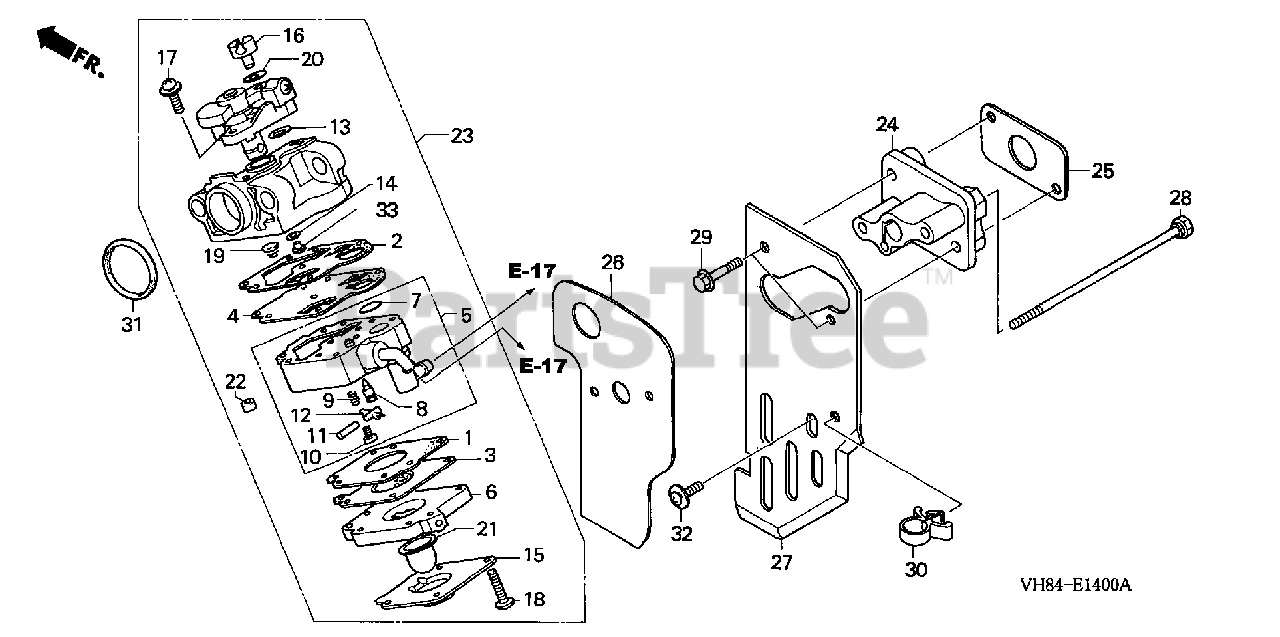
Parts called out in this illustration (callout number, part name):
1	GASKET, METERING DIAPHRAGM
2	GASKET, PUMP
3	DIAPHRAGM ASSY., METERING
4	DIAPHRAGM, PUMP
5	BODY ASSY., PUMP
6	BODY ASSY., AIR PURGE
7	SCREEN, INLET
8	VALVE, INLET NEEDLE
9	SPRING, METERING LEVER
10	SCREW, METERING LEVER PIN
11	PIN, METERING LEVER
12	LEVER, METERING
13	RING, SPRING RETAINING
15	COVER, PRIMER PUMP
17	SCREW, THROTTLE COLLAR
18	SCREW, PUMP COVER
19	SPRING, PUMP
21	PUMP, PRIMER
22	FILTER, FUEL INLET
23	CARBURETOR ASSY. (WYL 127A)
24	INSULATOR, CARBURETOR
25	GASKET, INSULATOR
26	GASKET, CARBURETOR
27	GUIDE, AIR IN.
28	BOLT, HEX. (5X75)
29	BOLT, FLANGE (5X32)
30	CLIP, WIRE HARNESS
31	O-RING (14.8X2.4)
32	SCREW-WASHER (5X10)
33	JET (#33.5)
33	JET (#35.5)
